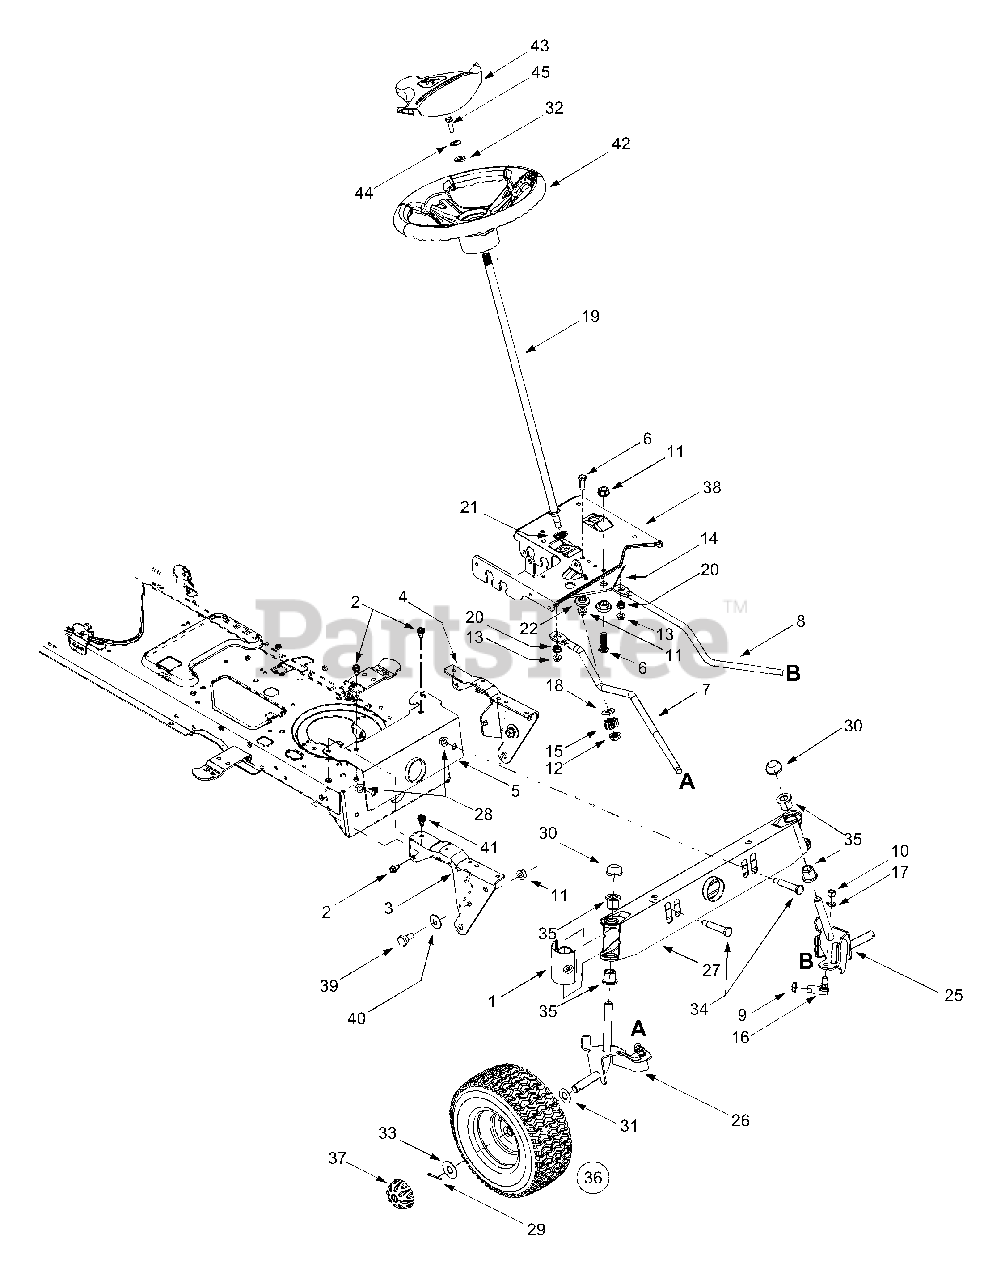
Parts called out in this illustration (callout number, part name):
1	Pivot Bar End Cap w/ Fitting
2	Self-tapping Screw, 16-18 x .625
6	Hex Cap Screw, 3/8-16 x 1.25 (Grade 5)
7	RH Drag Link
9	Jam Nut, 7/16-20
10	Hex Nut, 3/8-24
11	Lock Nut, 3/8-16
12	Flange Lock Nut, 7/16-20
13	Lock Nut, 5/16-18
14	Steering Gear, 11/90 Ratio
15	Steering Pinion Gear
16	Ball Joint, 7/16-20
18	Flat Washer, .51 x 1.12 x .06
19	Steering Shaft, .625 OD x 24.4
20	Plastic Bushing, .38 ID
21	Hex Flange Bearing, 5/8
22	Shoulder Spacer, .38 ID
23	Standard Steering Wheel, 13.25
24	Steering Wheel Cap, Round
25	LH Axle Assembly, .750 Diameter
26	RH Axle Assembly, .750 Diameter
28	Lock Nut, 3/8-16
30	Push Cap, .625
31	Flat Washer, .64 x 1.0 x .12
32	Flat Washer, .406 x .875 x .105
33	Flat Washer, .635 x 1.589 x .06
34	Shoulder Screw, .5 x 2.2, 3/8-16
35	Flange Bearing
37	Deluxe Hub Cap
39	Shoulder Screw, 3/8-16
40	Bell Washer, .39 x 1.13 x .062
41	Self-tapping Screw, 5/16-18 x .75
42	Steering Wheel, Soft Grip, Three Spoke
43	Steering Wheel Cap, Round
45	Hex Bolt, 5/16-18 X 1
